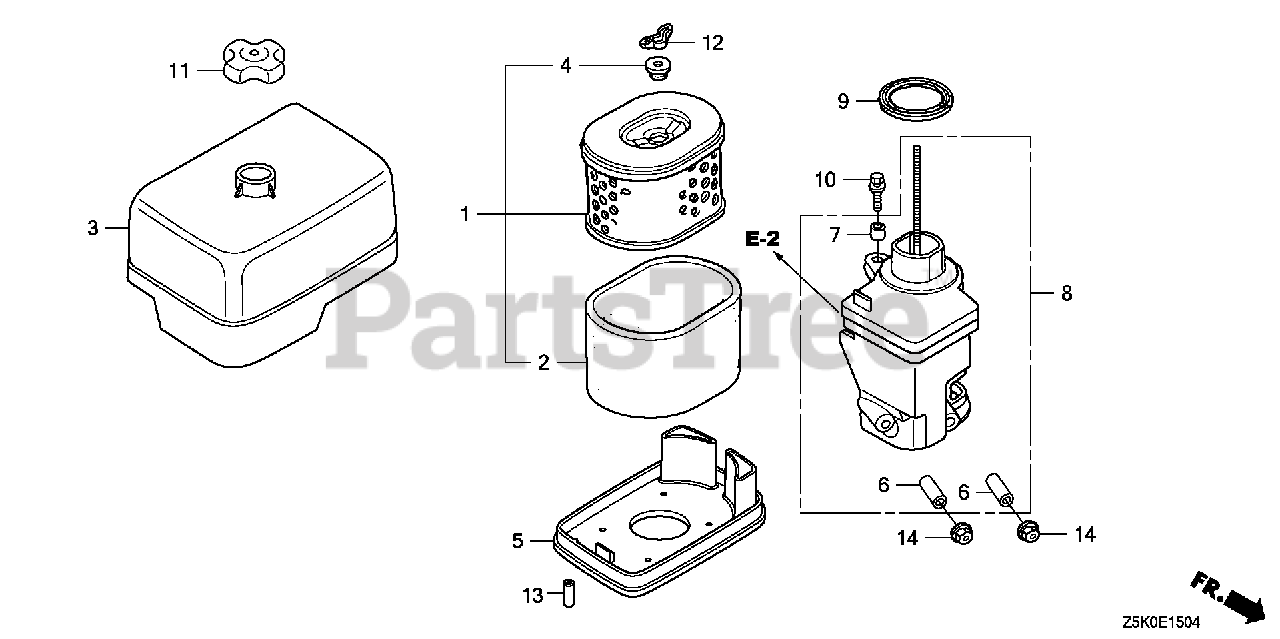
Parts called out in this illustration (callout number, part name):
1	ELEMENT, AIR CLEANER (DUAL)
2	FILTER (OUTER)
3	COVER, AIR CLEANER HOUSING
4	GROMMET, AIR CLEANER
5	NOSE, MUFFLER
6	COLLAR, AIR CLEANER
7	COLLAR B, AIR CLEANER
8	ELBOW, AIR CLEANER
9	GASKET, AIR CLEANER HOUSING
10	BOLT-WASHER (6X22)
11	NUT, AIR CLEANER COVER
12	NUT, TOOL BOX SETTING
13	CAP, SEALING
14	NUT, FLANGE (6MM)
